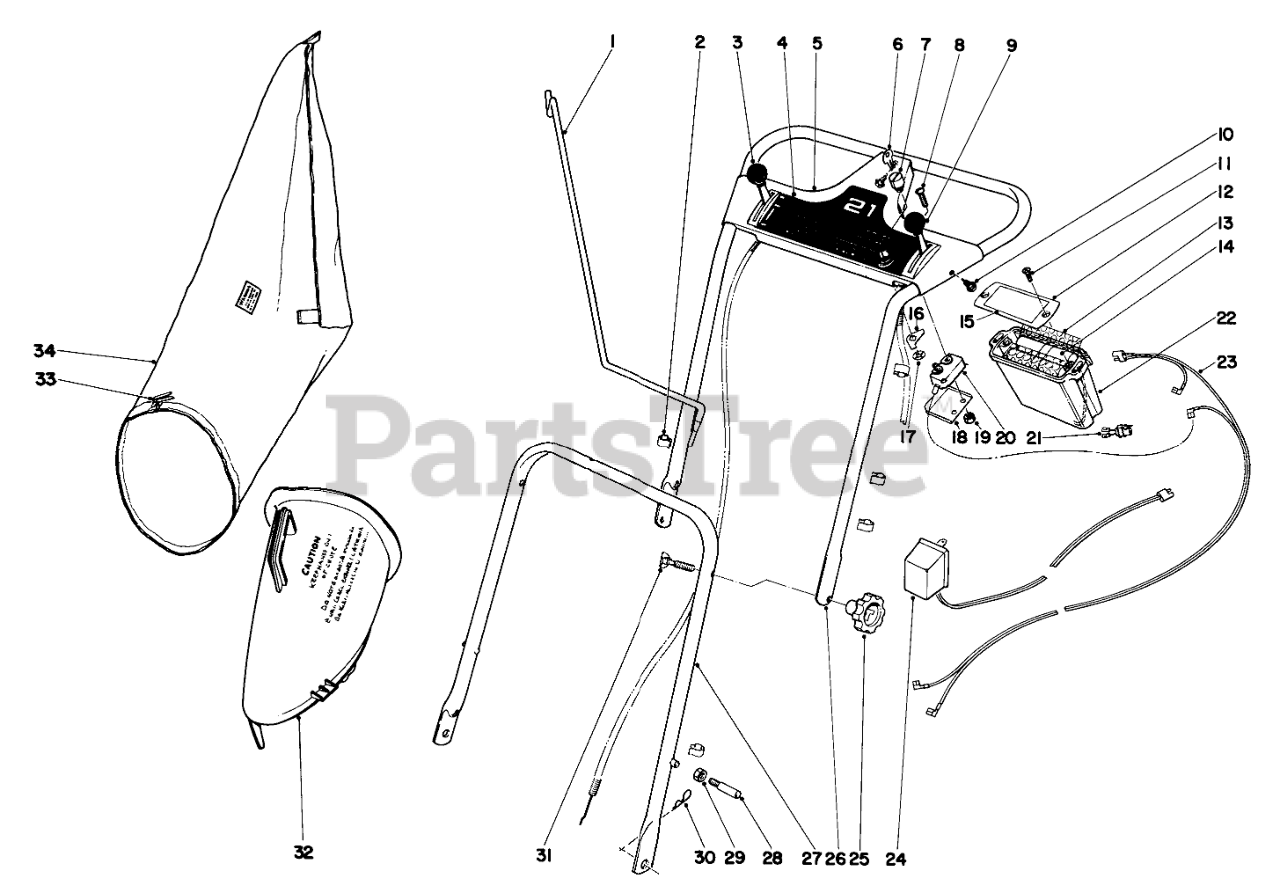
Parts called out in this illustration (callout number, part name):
1	BAG HANGER ROD
2	CONTROL WIRE CLIP
3	Throttle Control
4	Decal-Escutcheon Plate
5	Escutcheon Plate
7	Key Hsg.
9	Traction Control
10	SCREW-HWHTF
12	Cover
13	Spacer
14	Battery Pack
15	Decal
18	Cover Switch
19	NUT-KEPS
20	Switch
21	Plug & Wire
22	Container Pack
23	Wire Harness
24	Charger
25	Handle Release Knob
26	Upper Handle
27	Lower Handle
28	Handle Pin
29	Nut
30	PIN-COTTER, HAIR
31	HANDLE SCREW
32	BAG ATTACHMENT
33	BAG CORD FASTENER
34	Grass Bag (Incl. Ref. No. 33)
